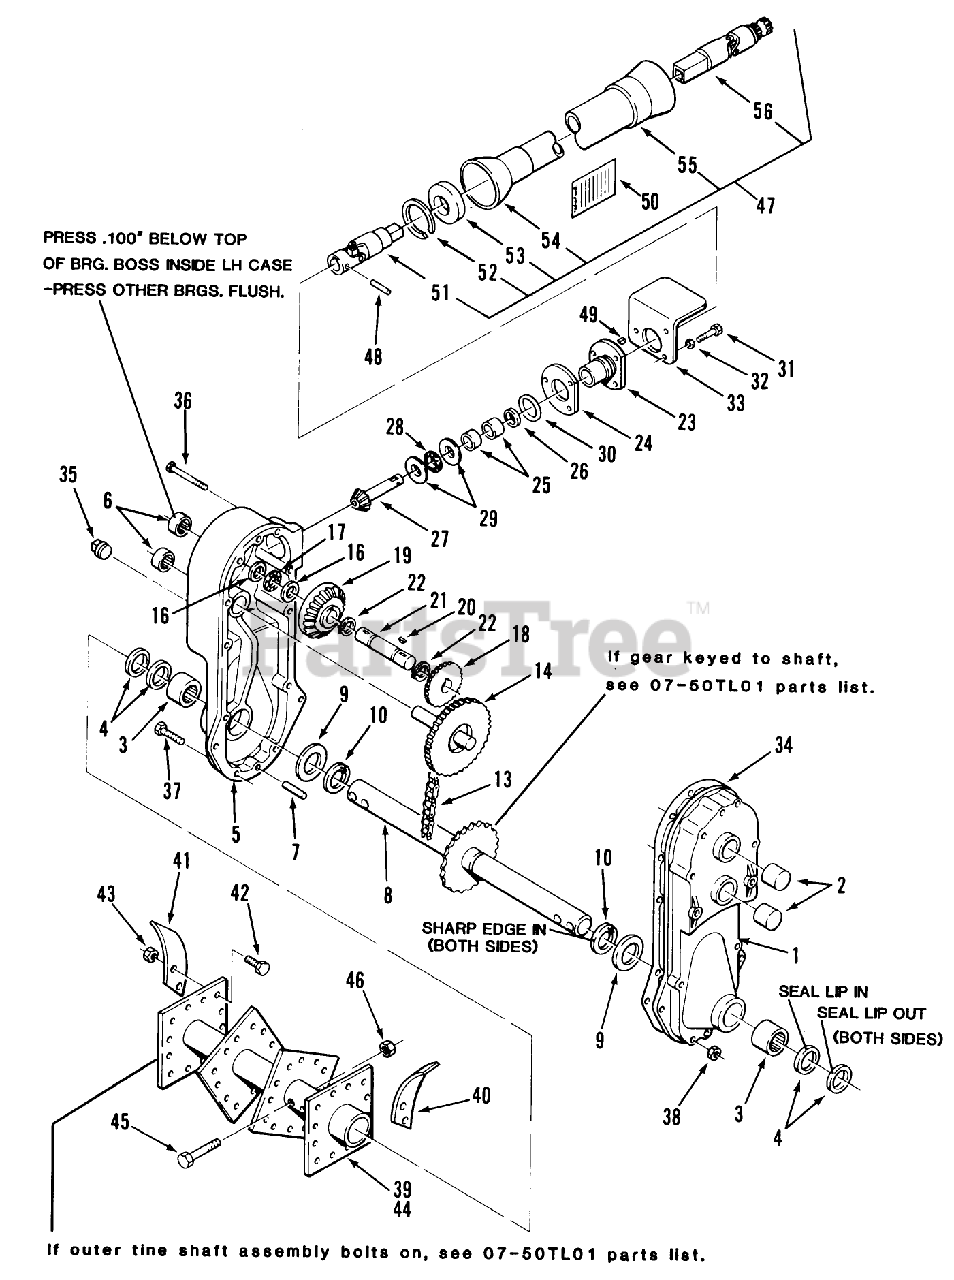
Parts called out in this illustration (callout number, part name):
1	Case-R.H.
2	BEARING-NEEDLE 1X1
3	Needle Bearing 11/2 x 1
4	SEAL-OIL
5	Case-L.H.
6	BEARING-NEEDLE
7	ROLL PIN 3/8 X 1
8	Tine Shaft & Gear
9	Washer
10	Snap Ring 1 1/2 Dia.
13	Chain #60-3/4 P x 44 P
14	GEAR ASSY
16	WASHER-THRUST
17	BEARING-THRUST
18	GEAR
19	Bevel Gear 40 T
20	KEY-WOODRUFF
21	SHAFT
22	Snap Ring
23	HOUSING-INPUT SHAFT
24	Gasket
25	BEARING-NEEDLE
26	SEAL-OIL
27	PINION&SHAFT
28	Bearing-Thrust
29	SHIM WASHER
30	O-RING
31	BOLT
32	LOCKWASHER
33	PTO Shield
34	GEAR CASE GASKET
35	SOLID PIPE PLUG
36	H H C S
37	Screw-Hex. Hd.
38	NUT
39	R.H. Tine Shaft
40	TINE RH R
41	TINE LH
42	7/16-14 x 1 1/4 Bolt
43	Nut
44	L.H. Tine Shaft
45	Bolt 5/8-11 x 2 3/4
46	E.S. Nut 5/8-11
47	Drive Shaft Assembly
48	SPIROL PIN
49	KEY-WOODRUFF
50	DECAL-DANGER
51	U-Joint with tube
52	Bearing Retainer
53	Bearing
54	ASSY SHIELD
55	Shield-2"
56	U-Joint with shaft
